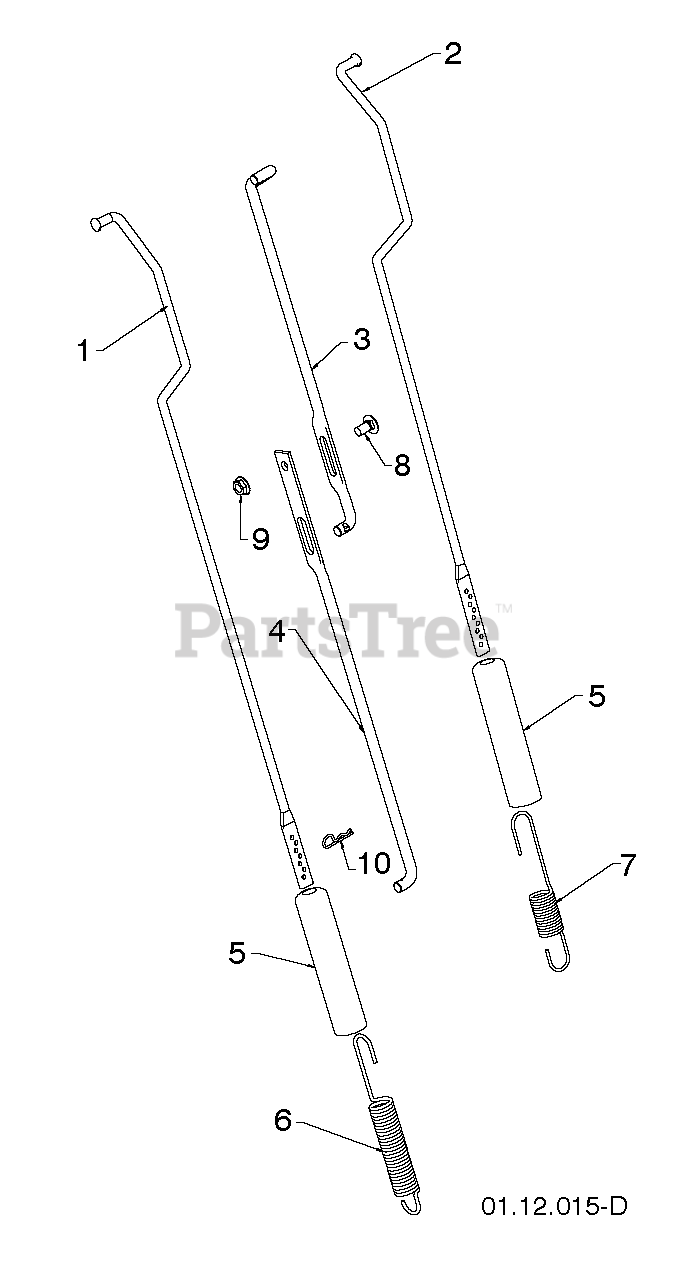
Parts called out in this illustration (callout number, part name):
1	ROD.IMPELLER
2	ROD.TRACTION
3	ROD.SHIFTER.TOP.HYD.SNOW
4	ROD, LOWER, SPEED CONTROL
5	SLEEVE, SPRING
6	SPRING.CONTROL.ROD.SNOW
7	SPRING.TRACTION.ROD.SNOW
8	BOLT
9	NUT.FLANGE.5/16
10	SPRING RETAINER
